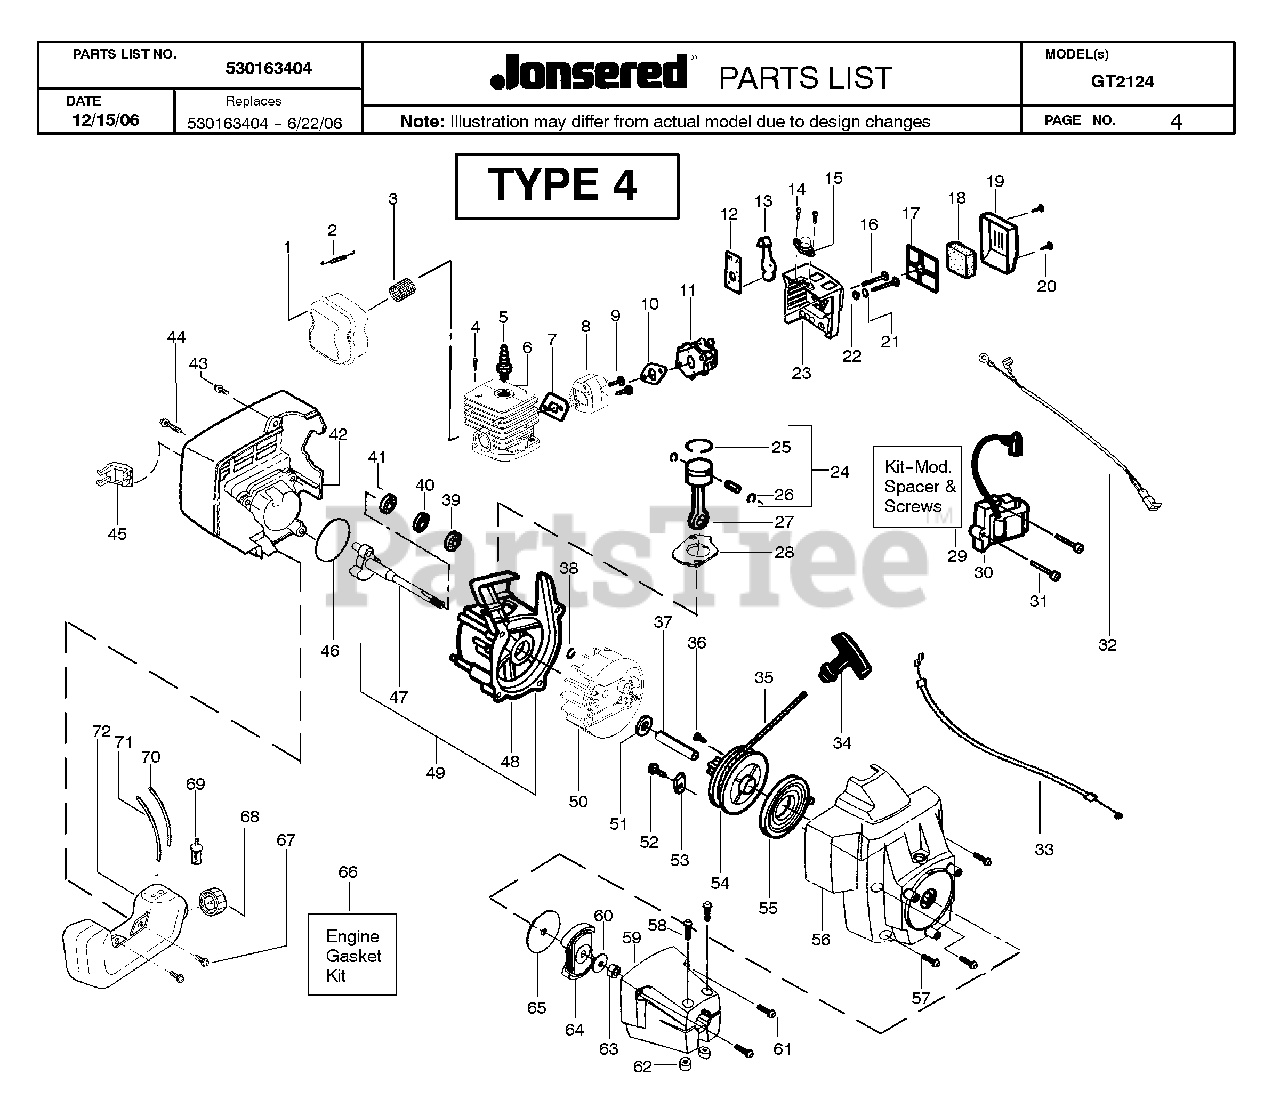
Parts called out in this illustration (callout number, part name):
1	KIT-MUFFLER
5	PLUG-SPARK (RCJ-6Y)
7	GASKET KIT
9	SCREW - CARB. ADAPTOR
10	GASKET KIT
11	CARBURETOR
12	CHOKE PLATE
13	CHOKE SHUTTER
14	SCREW - PRIMER ASSEMBLY
15	AIR PURGE BUBBLE
17	FILTER PLATE
18	AIR FILTER FOAM
19	AIR FILTER COVER
20	SCREW FILTER PLATE
21	CHOKE SPACER
24	PISTON KIT
25	PISTON RING
26	WRIST PIN RET.
28	GASKET KIT
30	IGNITION MODULE
32	LEAD WIRE ASSEMBLY
34	HANDLE-STARTER
36	SCREW SEMS TOOTHED WASHER
38	RETAINING RING
39	OUTER BEARING
40	KIT-CRANKCASE SEAL
41	BEARING
44	SCREW - SHROUD
46	GASKET KIT
47	CRANKSHAFT ASSEMBLY
50	FLYWHEEL
52	SCREW 8-16 X 9/16 (PLAS
54	STARTER PULLEY KIT
55	STARTER SPRING
57	SCREW - SHROUD
58	SCREW-10-24 X 1-3/8 (UN
59	CLUTH COVER
60	WASHER FLAT
61	SCREW-10-14 X 13/16 (PL
62	LOCKNUT-HEX 10-24
64	CLUTCH ASSEMBLY KIT
65	FRICTION DISC,CLUTCH 36/41
66	GASKET KIT
68	CAP ASSY W/ RETAINER
69	FUEL PICK-UP ASSY
